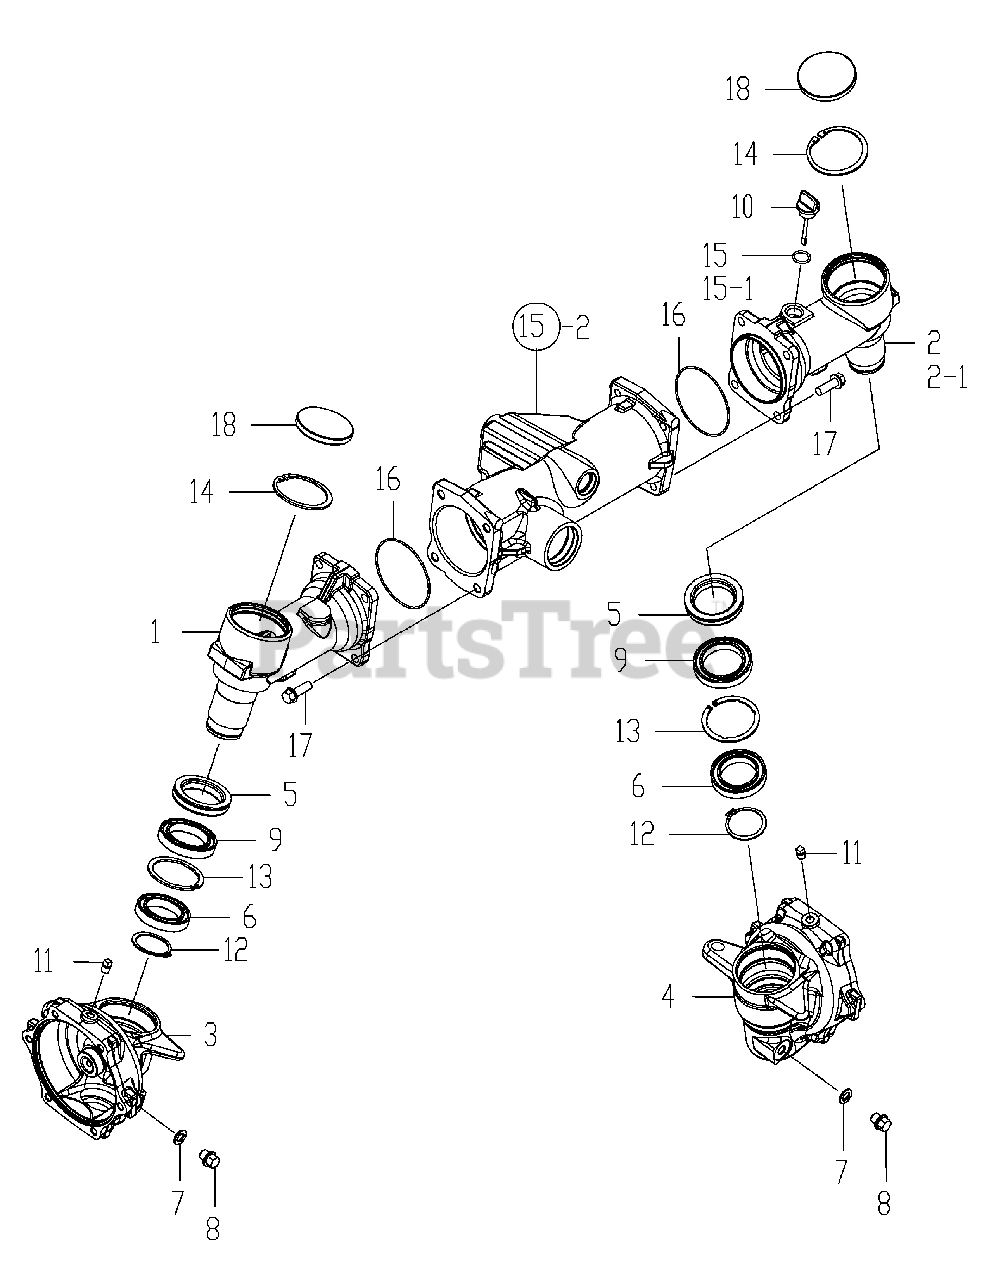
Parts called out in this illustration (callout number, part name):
1	CASE L,FRONT GEAR
2	CASE R,FRONT GEAR
2-1	CASE R,FRONT GEAR
3	BOX L,FRONT GEAR
4	BOX R,FRONT GEAR
5	SEAL QLN 50721013
7	GASKET, 20X12X2
10	GAUGE,OIL LEVEL
15	O-RING 18
15-1	PACKING, P 18.0
16	PACKING, S 90.0
18	CAP, SEALING 72
